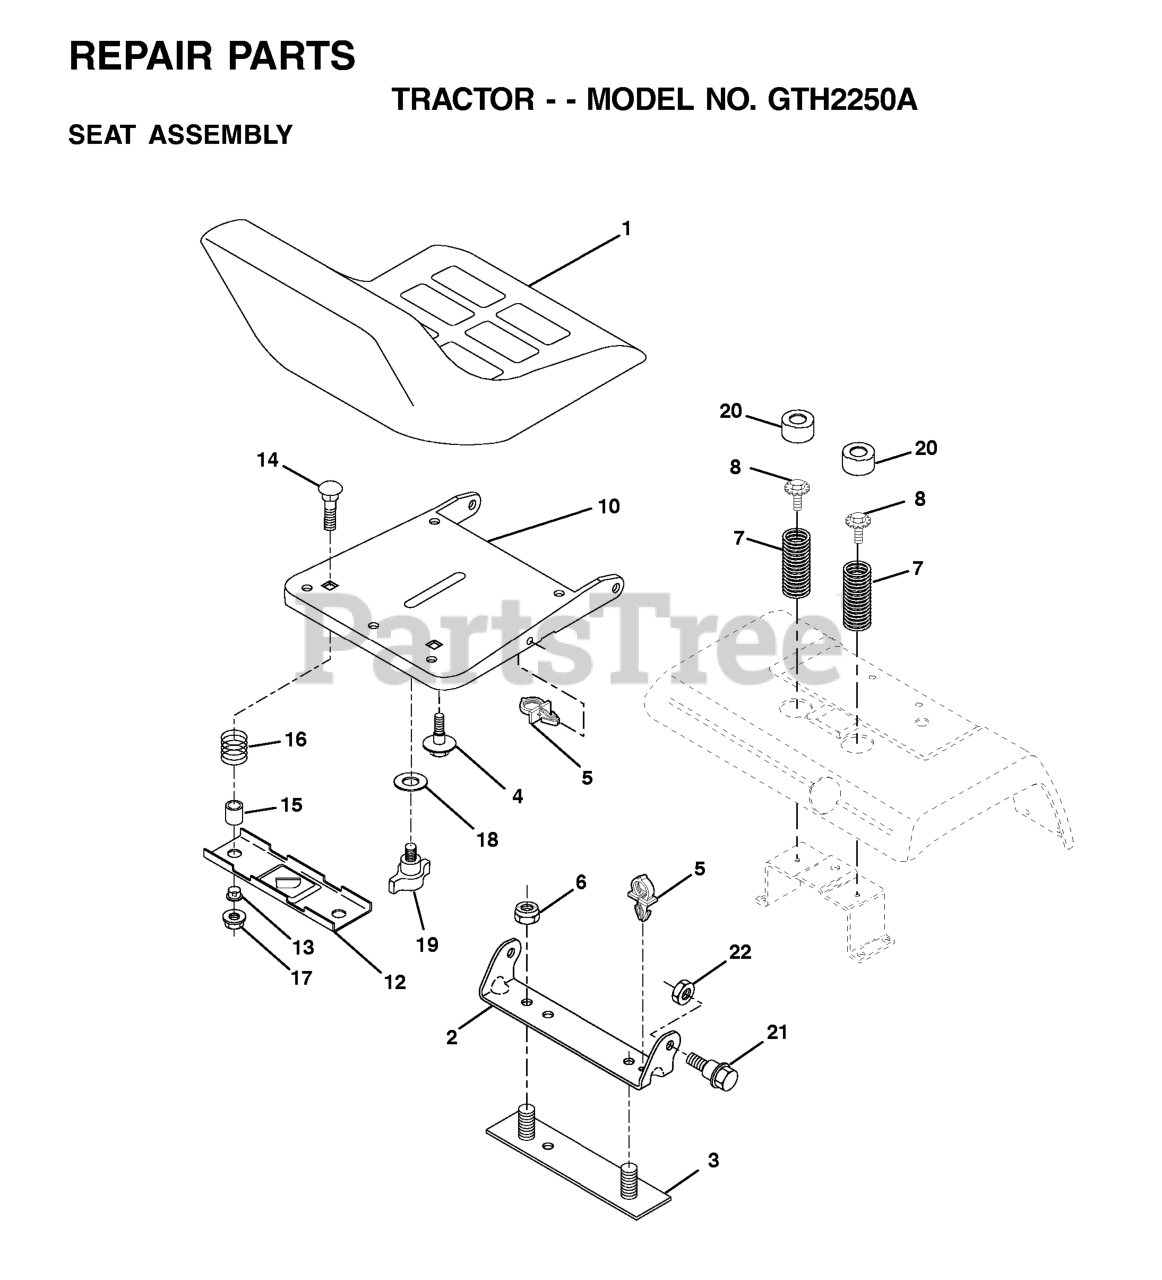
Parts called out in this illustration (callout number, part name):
1	SEAT, GRAY
2	SEAT PIVOT BRKT
3	STRAP
4	BOLT,SHOULD
6	NUT
7	SPRING COMPRESSION
8	BOLT.5/16-18UNCX3/4 W/SEMS.BLK
10	PAN, SEAT
12	BRKT SWITCH
14	BOLT.ROUND.HEAD.SQUARE.NECK
15	SPACER SPLIT
16	SPRING COMPRESSED
17	NUT T
19	KNOB.SEAT.ADJ.WINGNUT
20	CAP SPRING
21	BOLT.SHOULDER.5/16-18
22	NUT.71038.31-18.HEX.NYLOCK
